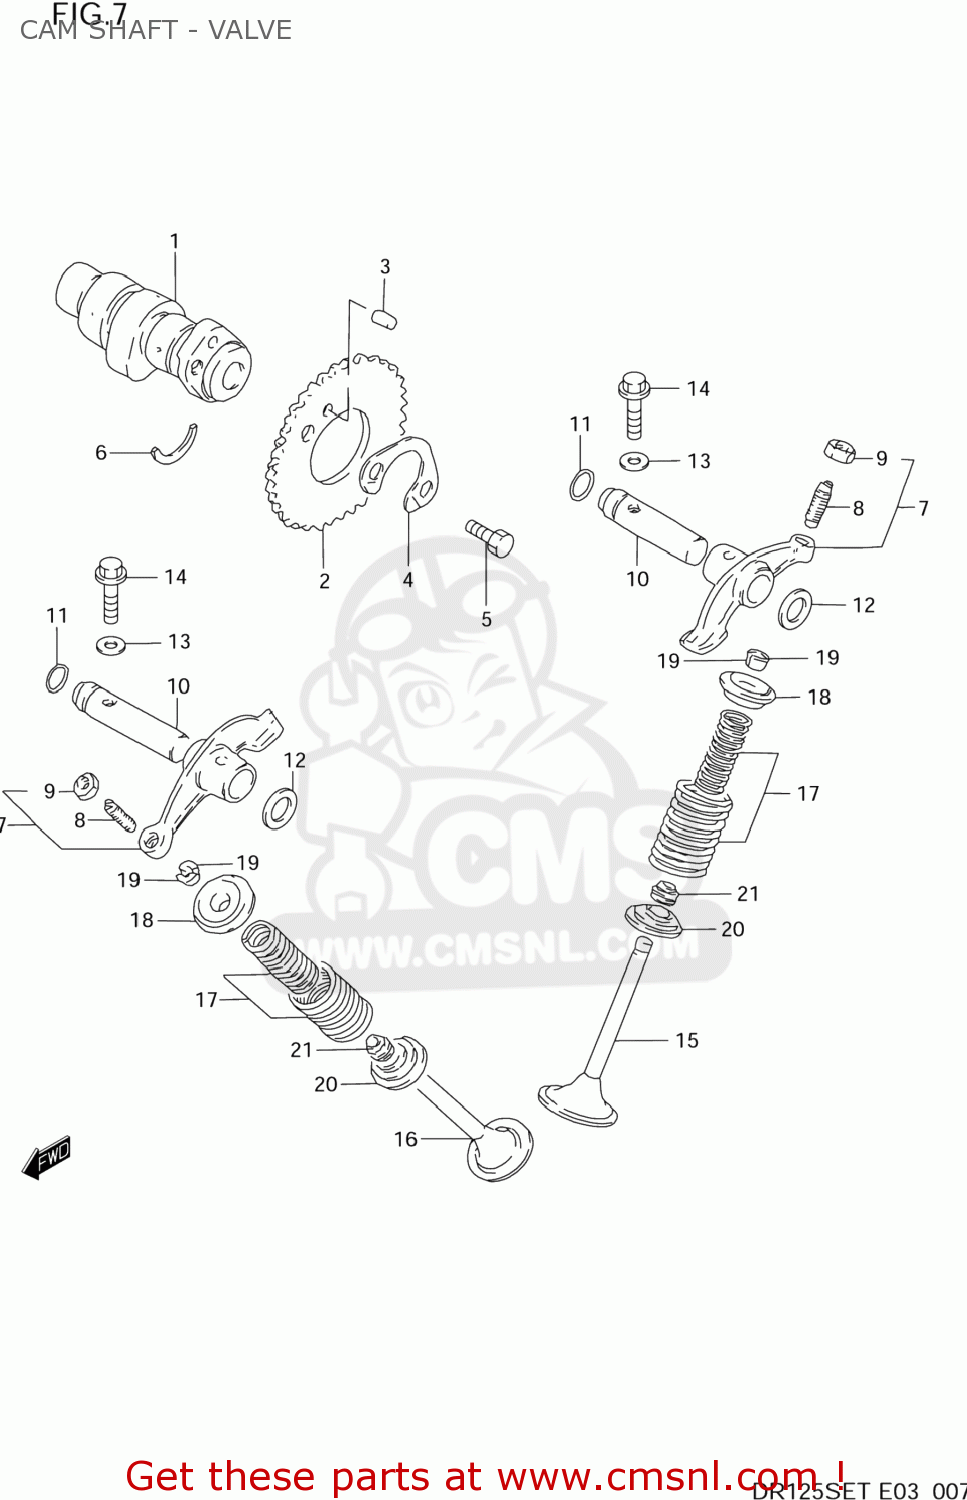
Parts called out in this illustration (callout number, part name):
1	CAMSHAFT
2	SPROCKET,CAMSHAFT
3	PIN(5X8)
4	WASHER,SPROCKET
5	BOLT(6X10.5)
6	C RING
7	ARM,VALVE ROCKER
8	SCREW,TAPPET ADJUSTING
9	NUT,ADJUSTING SCREW
10	SHAFT,VALVE ROCKET
11	O RING(D:1.9,ID:8.6)
12	WASHER
13	GASKET(5.8X13X1.2) (NAS)
14	BOLT
15	VALVE,INTAKE
16	VALVE,EXHAUST
17	SPRING SET,VALVE
18	RETAINER,VALVE SPRING
19	COTTER,VALVE
20	SEAT,VALVE SPRING
21	SEAL,OIL(5.5X11X8.2)
